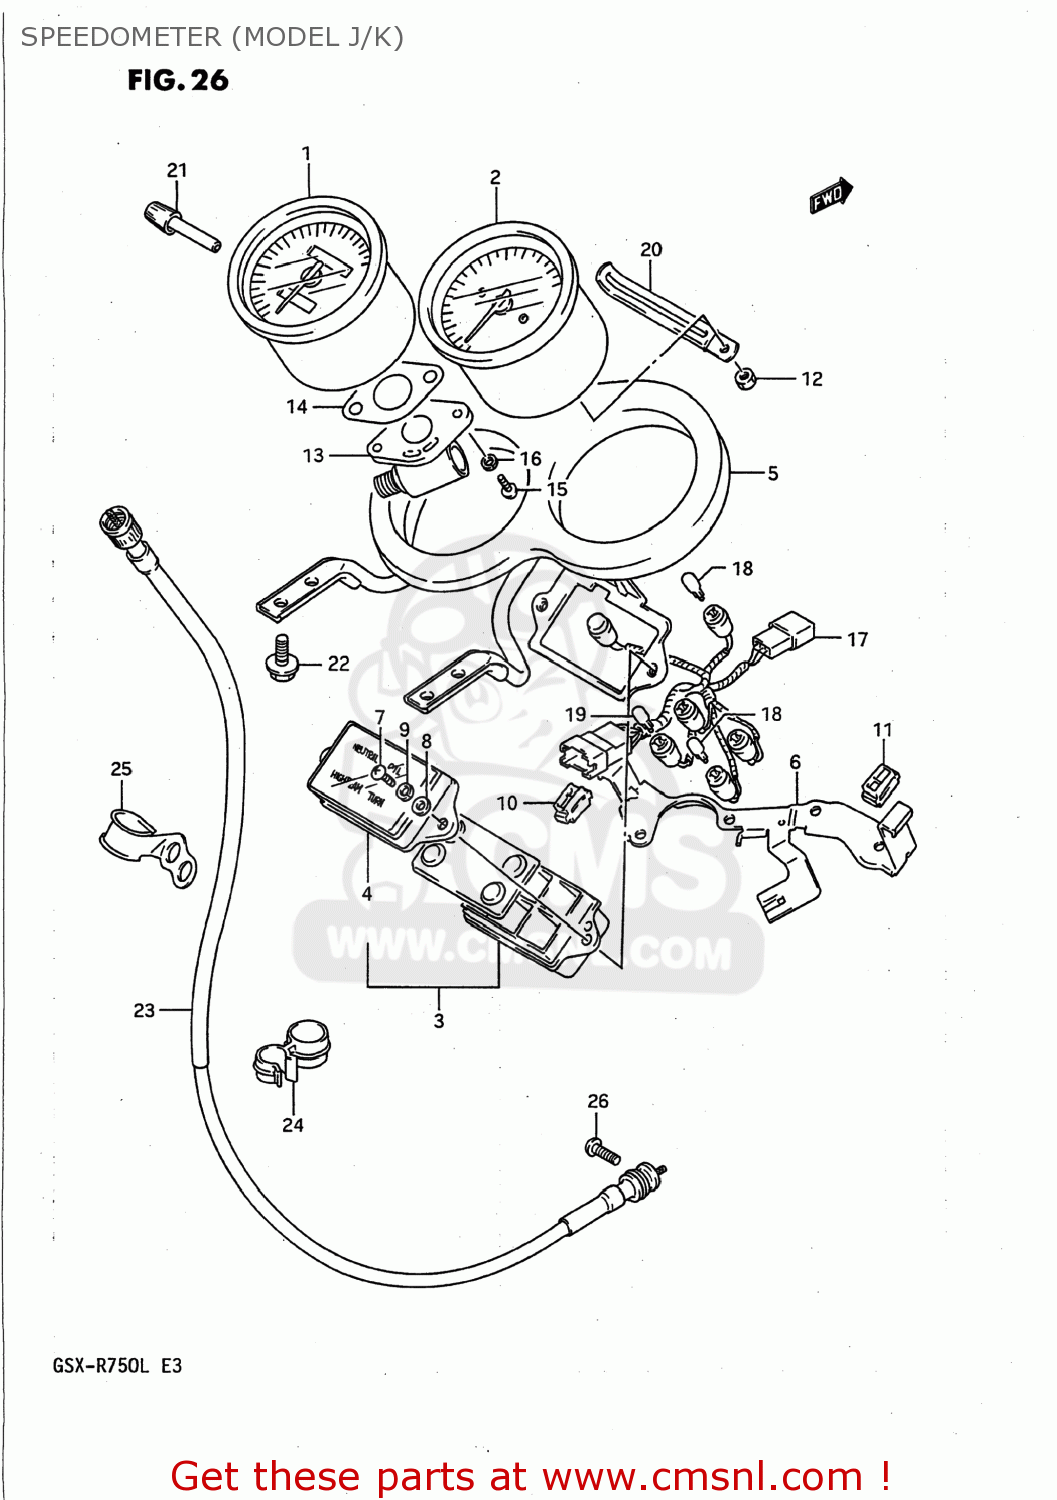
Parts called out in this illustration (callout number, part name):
1	SPEEDOMETER ASSEMBLY
2	TACHOMETER
3	BOX ASSEMBLY,PILOT LAMP
4	LENS,BOX
5	BRACKET,METER
6	BRACKET
7	SCREW
8	WASHER
9	WASHER,LOCK 4M
10	DAMPER,LEFT
11	CUSHION
12	NUT
13	GEAR BOX
14	GASKET,METER GEAR BOX (NAS)
15	SCREW
16	WASHER,LOCK 4M
17	SOCKET,METER
18	BULB(12V3W,T6.5)
19	BULB(12V1.7W,T6.5)
20	CLAMP
21	KNOB,TRIP
22	BOLT 6X12
23	CABLE ASSEMBLY,SPEEDOMETER
24	GUIDE,SPEEDOMETER CABLE
25	CLAMP,SPEEDOMETER CABLE
26	SCREW
